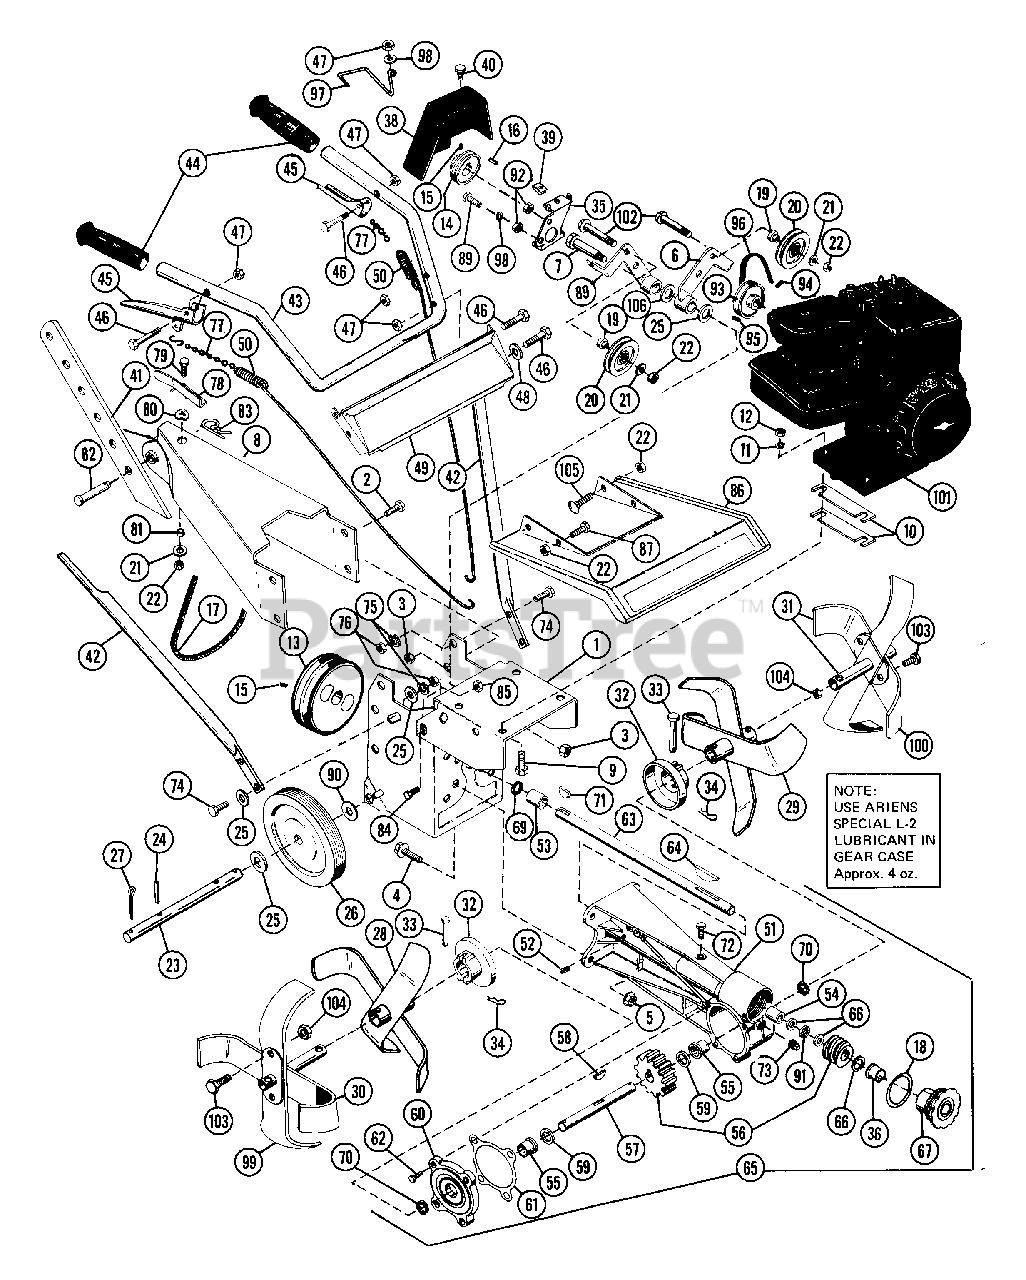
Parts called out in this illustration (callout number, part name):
1	FRAME
2	BLT-HEX .38-16X.75 PL GR2
3	NUT-LK-CTR .375-16 GR A PL
4	SCREW - FLG WIZ LOCK HH PL
5	NUT-LK-FLG .375-16 PL
6	IDLER ARM FWD
7	WHEEL SHOULDER BOLT
8	DEPTH STICK HOLDER
9	BLT-HEX .31-18X1.75 PL GR2
10	SHIM
11	WSHR-LK .312X.097 PL HVY
12	NUT-HEX .312-18
13	PLY-DBLV 5.50 X.75 W/KEY SALEM
14	ENGINE SHEAVE
15	SET SCREW
16	KEY-SQ .188X1.0X.188 SAE 8630
17	V-BELT, 4L-WRAPPED
19	SPCR, BRG .315X.50X.688X.281
20	IDLER
21	WSHR-FL-STL .38X.875X.083 PL
22	NUT-LK .312-18 GR A PL
23	AXLE ROD
24	PIN-ROLL .125X1.38
25	WSHR-FL-STL .531X1.062X.095 PL
27	PIN-COTR .12 X 1.25 PL
28	R H INNER TINE SPOOL
29	L H INNER TINE SPOOL
30	R H OUTER TINE SPOOL
31	L H OUTER TINE SPOOL
32	DUST CAP
33	CLEVIS PIN
34	PIN-HAIR INT .08X.38X1.42 YWZC
35	BELT GUARD BRACKET
36	BSHG-FLG .750X1.000X.750X1.132
38	BELT COVER
39	NUT-SPEED U-TYPE .250-20
40	BLT-HEX .25-20X.50 PL GR2
41	DEPTH STICK
42	LOWER HANDLE BAR
43	HANDLEBAR
44	GRIP
45	CLUTCH HANDLE
46	BLT-HEX .25-20X1.50 PL GR5
47	NUT-LK-CTR .250-20 PL
48	WSHR-FL-STL .268X.562X.046 PL
49	HANDLEBAR PANEL
50	SG-TENS .080X.25X31.6 WLD 35
51	GEARCASE - ALUMINUM
52	BREATHER
53	BSHG-SLV .750X1.000X1.000
54	BSHG-SLV .750X1.000X.750
55	BSHG-FLG 1.000X1.25X.75X1.50
56	WORM & GEAR SET
57	TINE SHAFT
58	KEY-WDRF .25X.687X.375
59	WSHR-HRD-THRS 1.007X1.542X.062
62	BLT-SERHFWH .31-18X.62 PL
63	WORM SHAFT
64	KEY-FTHR .188X1.38X.188
65	GEAR CASE ASSEMBLY
66	WSHR-HDND-THRST .755X1.40X.062
67	ADJUSTMENT PLUG
69	SEAL .750X1.000X.125
70	SEAL 1.000X1.980X.375
71	KEY-WDRF .188X.875X.375 SAE11
72	BLT-SCRHFWH .38-16X.50 PL
73	PIPE PLUG
74	BLT-HEX .38-16X1.00 PL
75	WSHR-LK .375X.115 HVY PL
76	NUT-HEX .375-16
77	CLUTCH CHAIN
78	RETAINER CLIP
79	BLT-HEX .31-18X.75 PL GR2
80	WAVE WASHER .515 X 1.00 X .125
81	SPACER BUSHING .5 X .32 X .21
82	CLEVIS PIN .437/.431X1.50 YWZC
83	PIN-HAIR INT .12X2.75
84	BLT-HEX .38-16X.75 PL GR5
85	NUT-LK TOP .375-16 GR C YWZC
86	TINE HOOD
87	BLT-HEX .31-18X.63 PL GR 2
88	WSHR-FL-STL.312X.734X.065PL
89	IDLER ARM REV.
90	SPACER .76 X .51 X .56
91	BRG-N THRST .754X1.24X.078
92	NUT-LK-FLG .250-20 PL
93	REVERSE SHEAVE
94	SCR-SET .25-20X.25 SKHCUPNY OH
95	KEY-WDRF .125X.625X.250 SAE5
96	V-BELT, 3L-WRAPPED
97	BELT FINGER
98	WSHR-FL-STL.281X.62X.065 PL
99	R H TURBO-TINE
100	L H TURBO-TINE
102	BLT-RDHDSQNK .31-18X1.25 SHTPL
103	BLT-HEX .44-14X1.00 GR5
104	NUT-LK-TOP .437-14 GR C PL
105	BLT-RDHDSQSHNK .31-18X.50 YZ
106	WSHR-FL-STL .520X.827X.062 YZ
